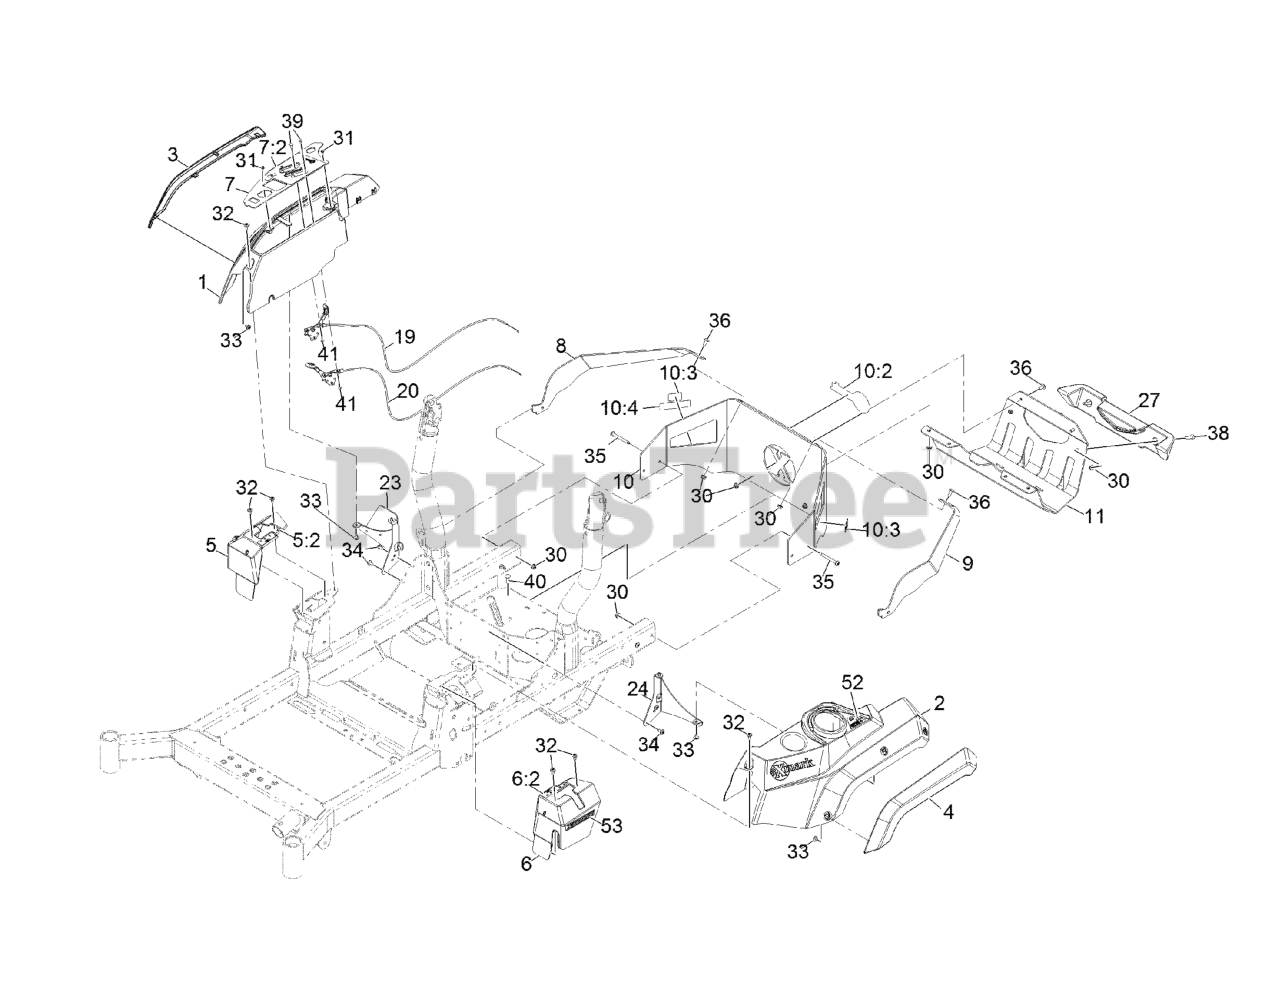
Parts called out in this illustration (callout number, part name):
1	CONSOLE-EXMARK, RH
2	CONSOLE, LH
3	FENDER-RH
4	FENDER-LH
5	COVER-CONTROL, MOTION (RH
5:2	Decal-Control, Motion (RH)
6	COVER-CONTROL, MOTION (LH
6:2	Decal-Control, Motion (LH)
7	CTRL PANEL ASM W/DECAL
7:2	DECAL-CONTROL PANEL
8	SUPPORT-UPPER, RH
9	SUPPORT-UPPER, LH
10	REAR GUARD ASM
10:2	DECAL-EXMARK LOGO
10:3	DECAL-WARNING
10:4	DECAL-ARRESTOR, SPARK
11	GUARD-MUFFLER
19	CABLE-CONTROL, CHOKE
20	CABLE-CONTROL, THROTTLE
23	SUPPORT-CONSOLE, RH
24	BRACKET-CONSOLE, LH
30	NUT-HF, NI
31	SCREW-HWH
32	SCREW-SHOULDER
33	SCREW-TORX
34	SCREW-TORX
35	SCREW-TORX
36	SCREW-TORX
38	SCREW-TORX
39	BOLT-CARR
40	SCREW-CARR
41	NUT-LOCK, NI
52	DECAL-FILL, FUEL
53	DECAL-X-SERIES
